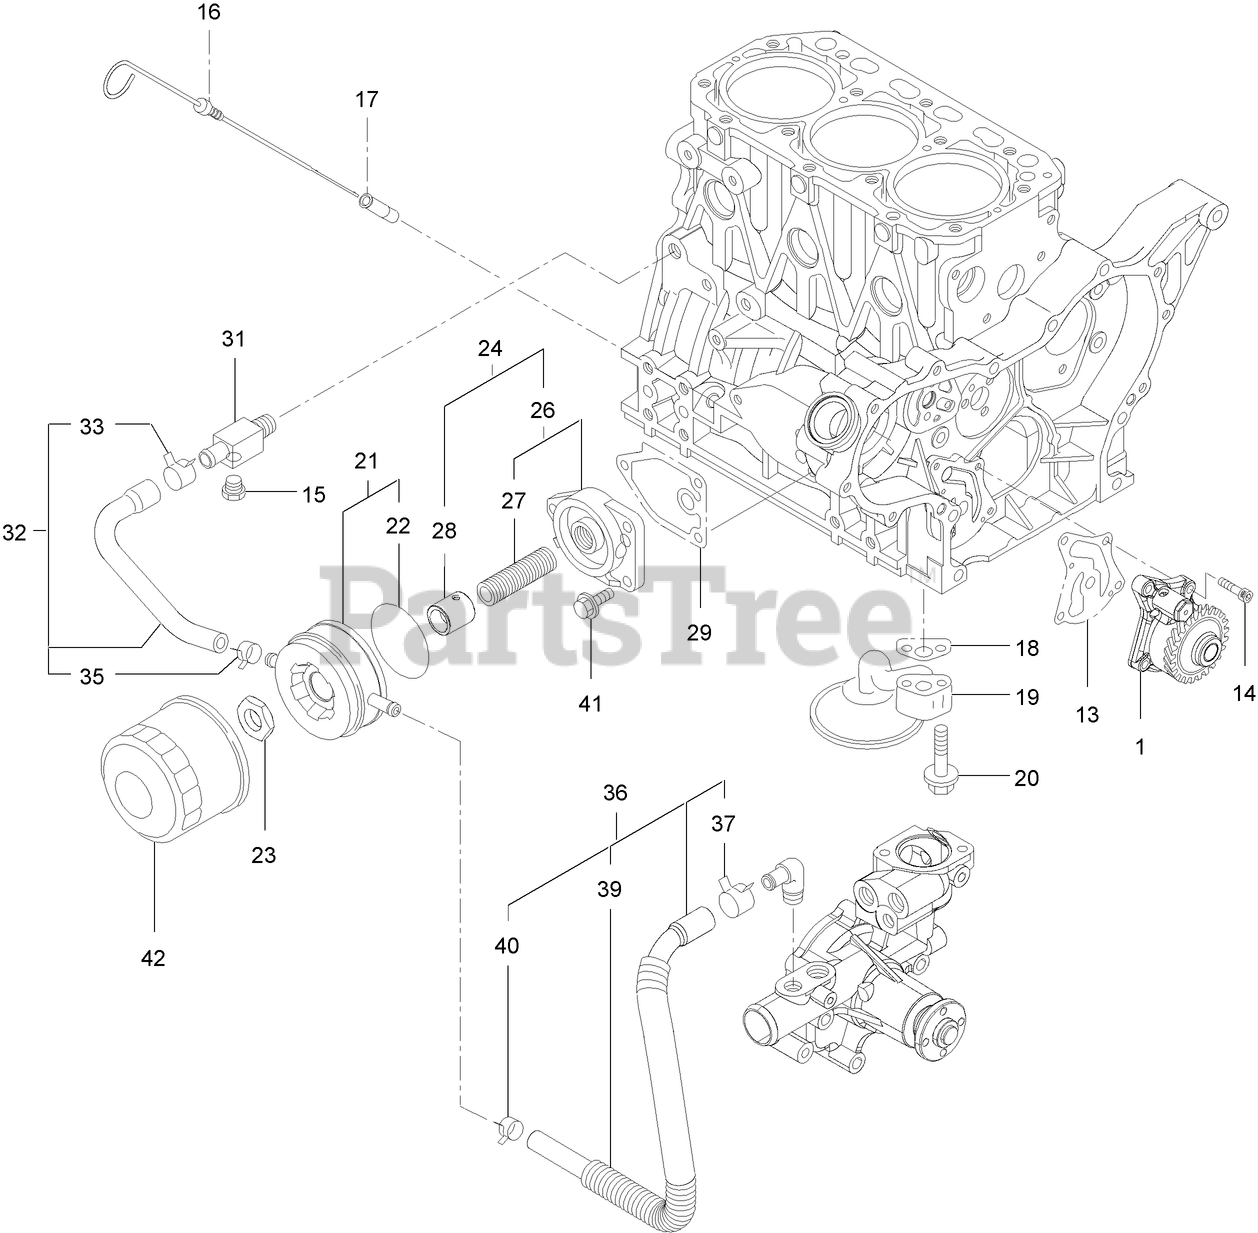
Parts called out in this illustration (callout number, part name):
1	OIL LUBE PUMP ASM
13	GASKET
15	PLUG-DRAIN
16	DIPSTICK-OIL
17	GUIDE-DIPSTICK
18	GASKET
19	PIPE ASM-OIL INLET
21	COOLER ASM-OIL
22	PACKING-OIL COOLER
24	BRACKET ASM-LO FILT
26	FILTER BRACKET ASM
28	COLLAR-OIL COOLER
29	GASKET
32	PIPE ASM
35	CLAMP-HOSE
36	PIPE ASM
40	CLAMP-HOSE
42	FILTER-ENGINE
